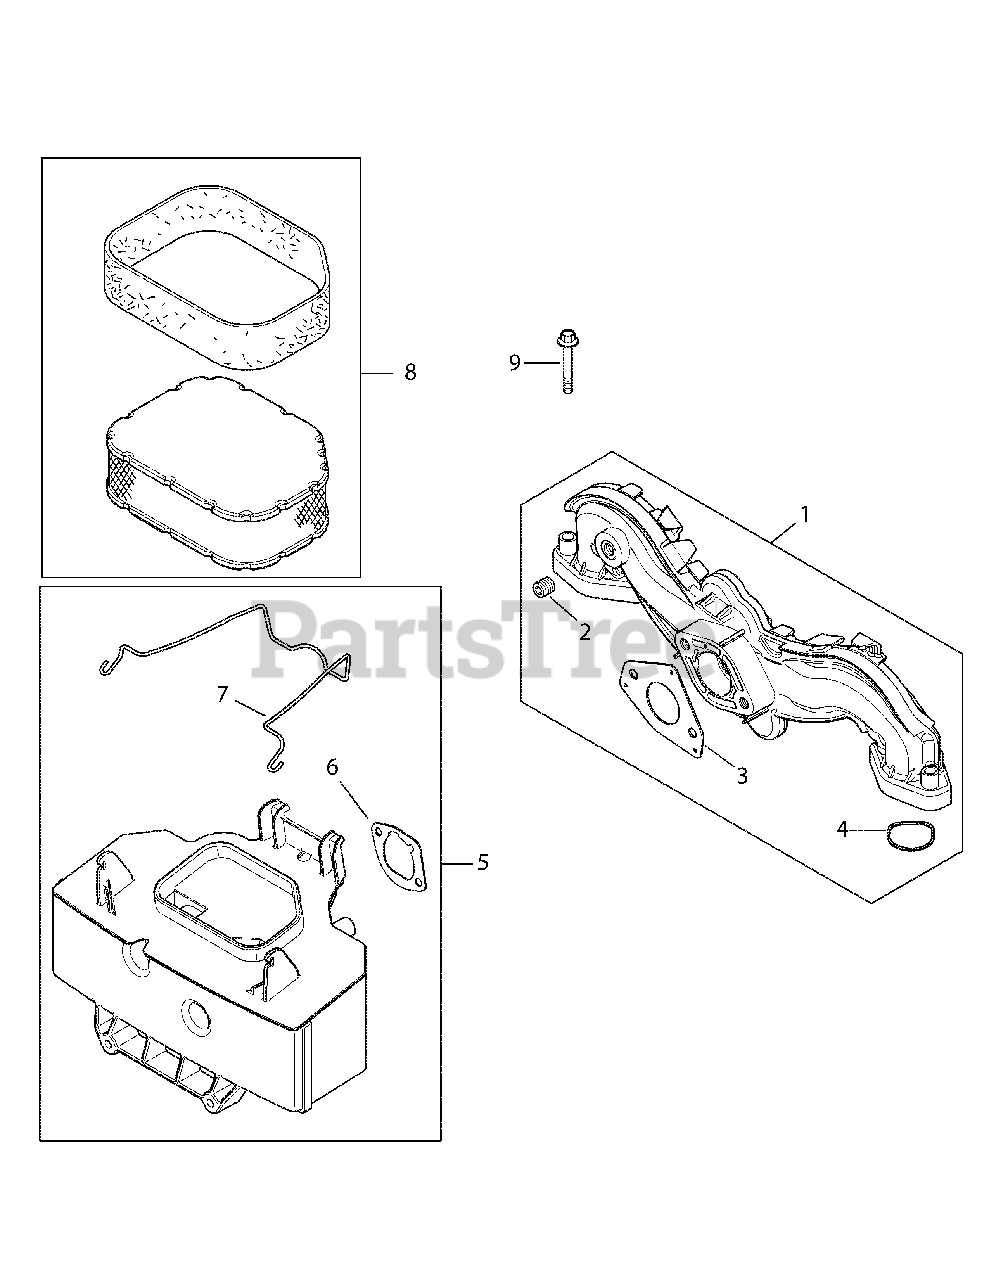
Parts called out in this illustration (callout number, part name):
1	Intake Manifold Kit (Inc. 2-4)
2	Carburetor Gasket
3	Intake Port O-Ring
4	Ctsk. Pipe Plug, 1.8
5	Air Cleaner Base Kit (Inc. 5 & 6)
6	Air Cleaner Base Gasket
7	Air Cleaner Element Latch
8	Air Filter Element / Pre-Cleaner
9	Flg. Screw, M6 X 1.0 X 40
